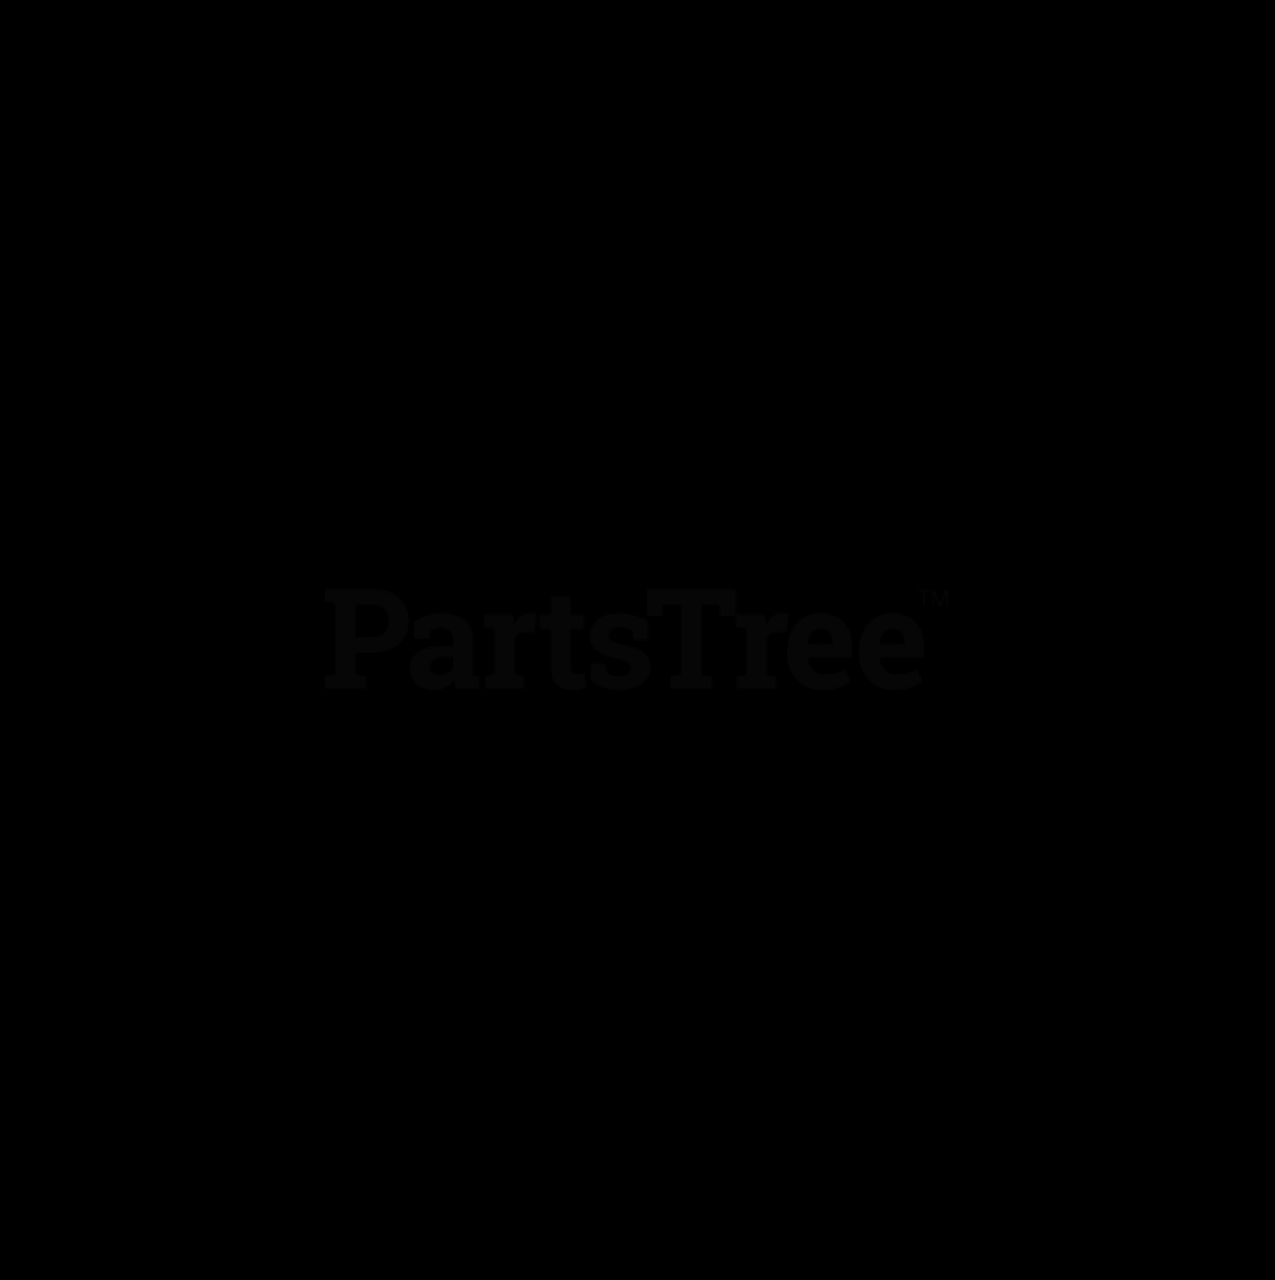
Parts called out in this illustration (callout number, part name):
1	Weldment, Frame
2	Weldment, Front Axle
3	Bushing, Flange 1.25 x 1.50 x 1.00 x .200
4	Fitting, Lube 45 Degree GM411031
5	Pin, Axle
7	Nut, Locking Nylon 1.0-14
8	Screw, Tapping .38-16 x .75
9	Axle Cover
10	Button, Bumper
11	Bolt, Hex .50-20 x 1.00 Grade 5
12	Panel, Inspection
13	Step, Ingress
14	Bolt, Round Head Square Neck .31-18 x 1.75 Grade 5
15	Nut, Locking Top Flange .31-18
16	Plate, Kick
17	Channel, Cross
18	Pulley, Idler
19	Nut, Retainer .375-16 x .37
20	Bolt, Serrated Flange Washer Head .38-16 x 1.00
21	Bolt, Hex .50-13 x 3.25 Grade 5
22	Bolt, Hex .50-13 x 2.25 Grade 5
23	Washer, Flat Steel .505 x .88 x .072
25	Nut, Spin Lock Flange .312-18
26	Washer, Flat Steel .064 x 1.810 x .250
27	Bolt, Hex .31-18 x 1.00 Grade 5
28	Washer, Flat Steel .64 x 1.75 x .250
29	Cable, Seat Prop
30	Guard, Grass
31	Bracket, Weight (992215, 216)
32	Weight, Cast Iron
33	Bolt, Hex .50-13 x 1.25 Grade 5
34	Nut, Locking Top Flange .50-13
35	Bolt, Hex .50-13 x 4.50 Grade 5
36	Washer, Flat Steel .531 x 1.06 x .095
37	Nut, Spin Lock, Flange .312-18
38	Weldment, Right Hand Axle Cover Support
39	Weldment, Left Hand Axle Cover Support
40	Bolt, Hex .38-16 x 3.00 Grade 5
41	Nut, Locking Top Flange .38-16
42	Plate, Backer
43	Spacer, 1.25 OD x 1.0 ID x 3.63
44	Plate, Guard, Debris (992218)
45	Screw, Tapping Hex Washer Head .38-16 x .50 TR (992218)
46	Bolt, Hex Washer Head .25-20 x .75 Grade 5 (992218)
47	Nut, Nylock, Flanged, .25-20 (992218)
48	Nut, Coupling .31-18 x 2.25 LG (992218)
49	Bolt, Hex .31-18 x .75 Gr 5 (992218)
50	Washer, Locking .31 x .078 Reg (992218)
51	Washer, Flange, Steel .344 x .688 x .065 (992218)
52	Spacer, .563 x 6.25 x .969 (992218)
53	Bracket, Guard Right Hand (992218)
54	Washer, Plated, Steel (992218)
55	Clamp, Steel (992218)
56	Bolt, .38-16 x 1.25 Grade 5 (992218)
57	Washer, Flat Steel .406 x .812 x .065 (992218)
58	Nut, Locking Top Flange .38-16 (992218)
59	Guard, Diesel Left Hand (992218)
60	Guard, Diesel Right Hand (992218)
61	Bushing, Flange .515 x .75 x .275
62	Washer, Flat Steel .563 x 1.38 x .109
